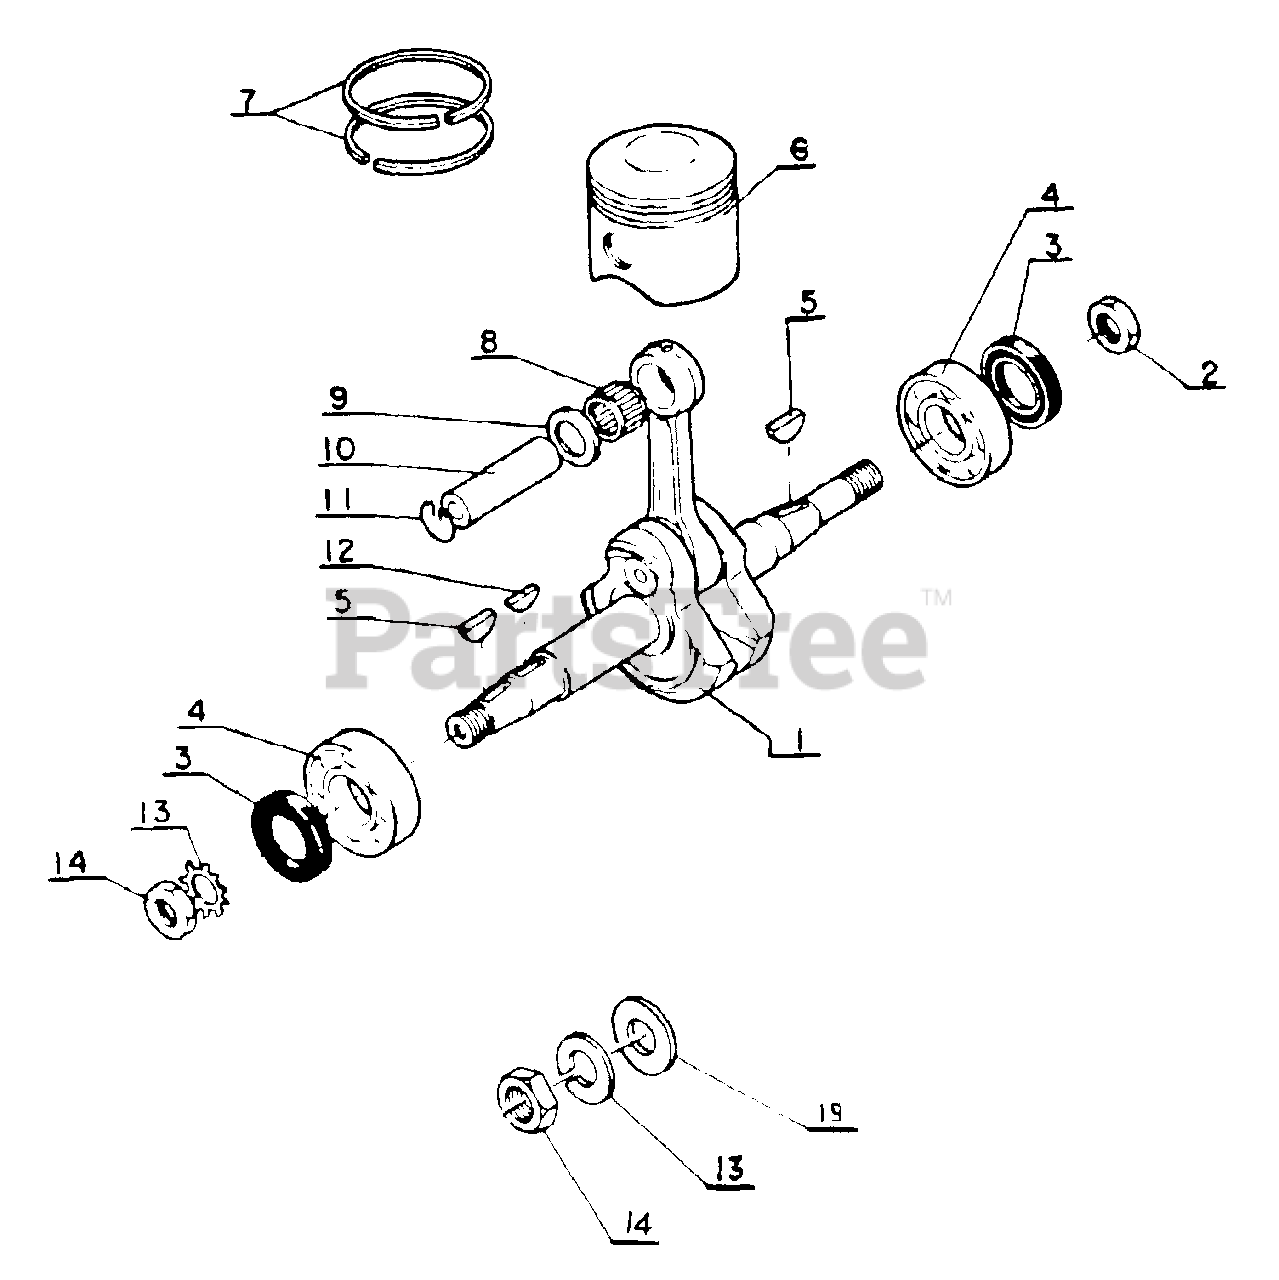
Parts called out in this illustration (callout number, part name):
1	CRANKSHAFT ASSY
3	SEAL, OIL
4	BEARING, BALL 6203 C3
5	KEY, WOODRUFF - 3×14
6	PISTON
7	RING, PISTON
8	BEARING, NEEDLE
9	WASHER, THRUST
10	PIN, PISTON
11	RING, SNAP
13	WASHER
19	WASHER
